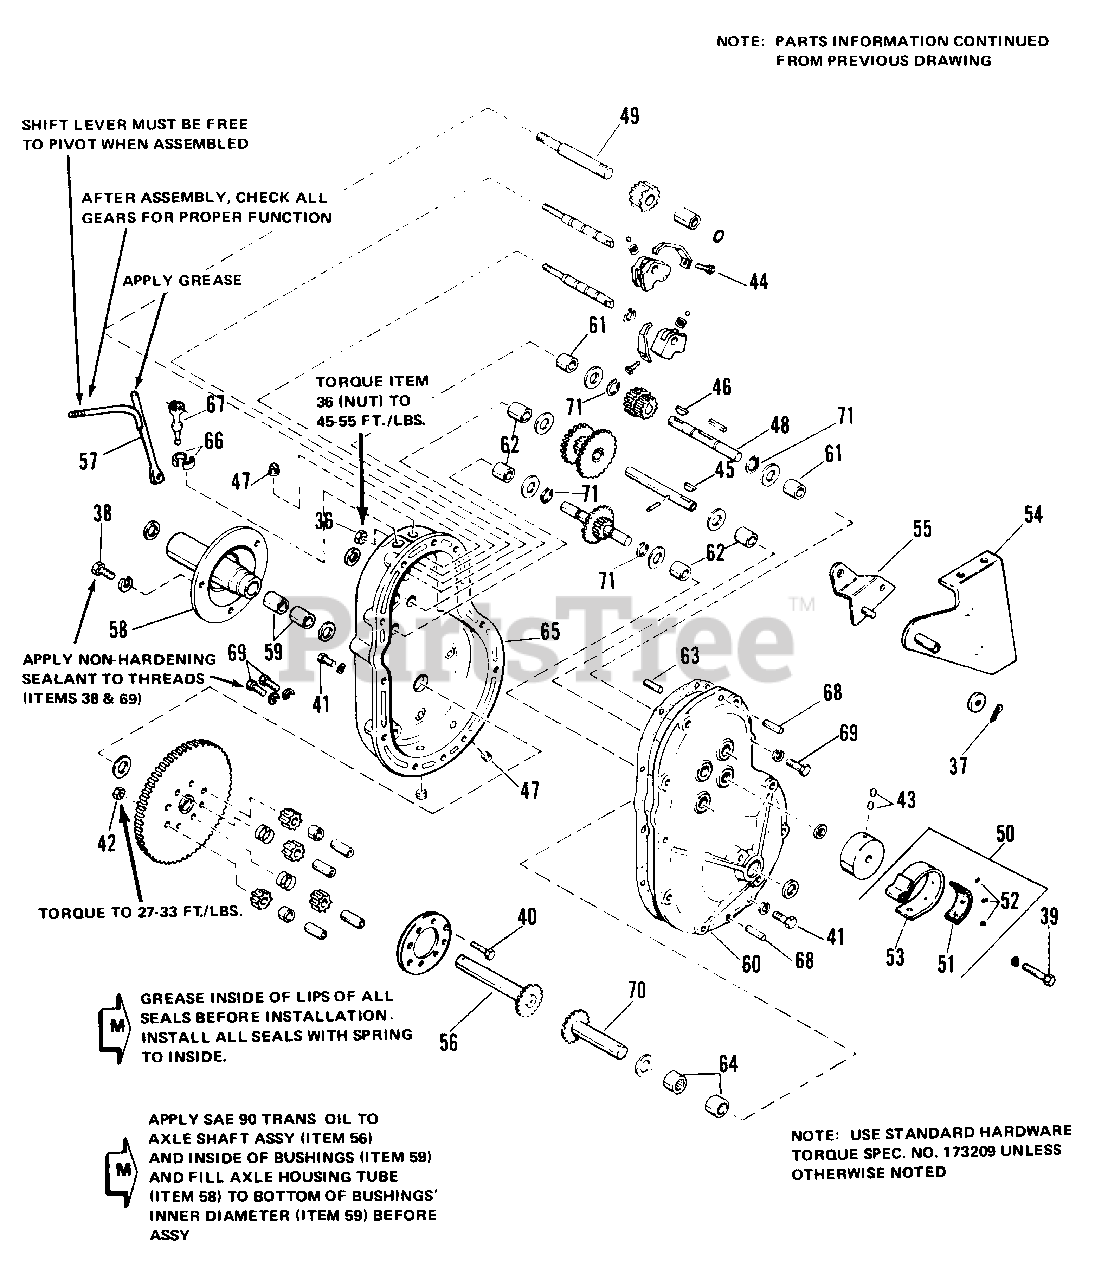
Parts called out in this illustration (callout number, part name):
36	NUT, Hex, 7/16-14
37	PIN, Cotter, 1/4 x 3/4
38	CAPSCREW, Hex Hd., 3/8-16 x 7/8
39	CAPSCREW, Hex Hd., 5/16-18 x 1-1/2
40	CAPSCREW, Hex Hd., 3/8-16 x 2-1/2
41	CAPSCREW, Hex Hd., 5/16-18 x 1-1/4
42	LOCKNUT, Flange, 3/8-16
43	SCREW, Set Hex Skt., 5/16-18 x 5/16
44	SCREW, Hex Washer Hd., 5/16-18 x 5/16
45	KEY, Hi Pro, 5/32 x 5/8
46	KEY, Hi Pro, 3/16 x 3/4
47	PIPE, Bushing, 3/4
48	SHAFT, Input
49	SHAFT, Reverse Pinion
50	BAND ASSY., Brake
51	LINING, Brake
52	RIVET, Tubular, 3/16 x 1/4
53	BAND, Brake
54	SUPPORT ASSY., Transmission
55	IDLER LEVER ASSY
56	AXLE ASSY., R.H. (03565)
57	ROD ASSY., Shift (03565)
58	HOUSING ASSY., Axle w/Bearings (03565)
59	BUSHING (03565)
60	COVER, Sub-Assembly-Gear Case (03565)
62	BEARING, Roller
63	PIN, Sub-Assembly, Roll
64	BEARING, Roller (03565)
65	GEAR CASE SUB-ASSY (03565)
67	ROD ASSY., Shift (03565)
68	PIN, Spring, 3/8 x 1
69	CAPSCREW, Hex Hd., 3/8-16 x 3/4
70	AXLE ASSY., L.H. (03565)
71	RING, Retaining
